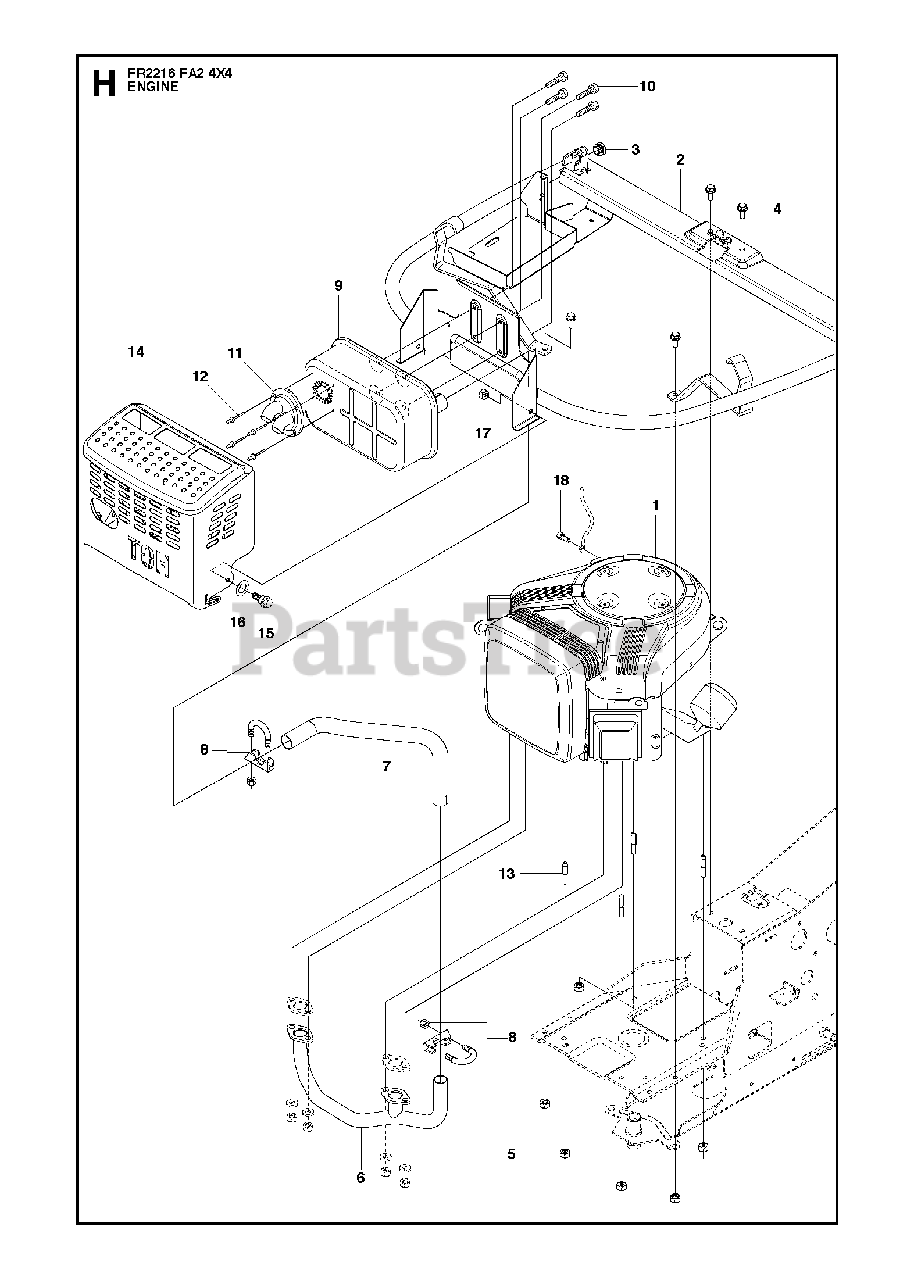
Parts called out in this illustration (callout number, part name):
5	LOCKNUT M8
9	MUFFLER
13	STUD SCREW
16	SPRINGWASHER
17	LOCKNUT M8
